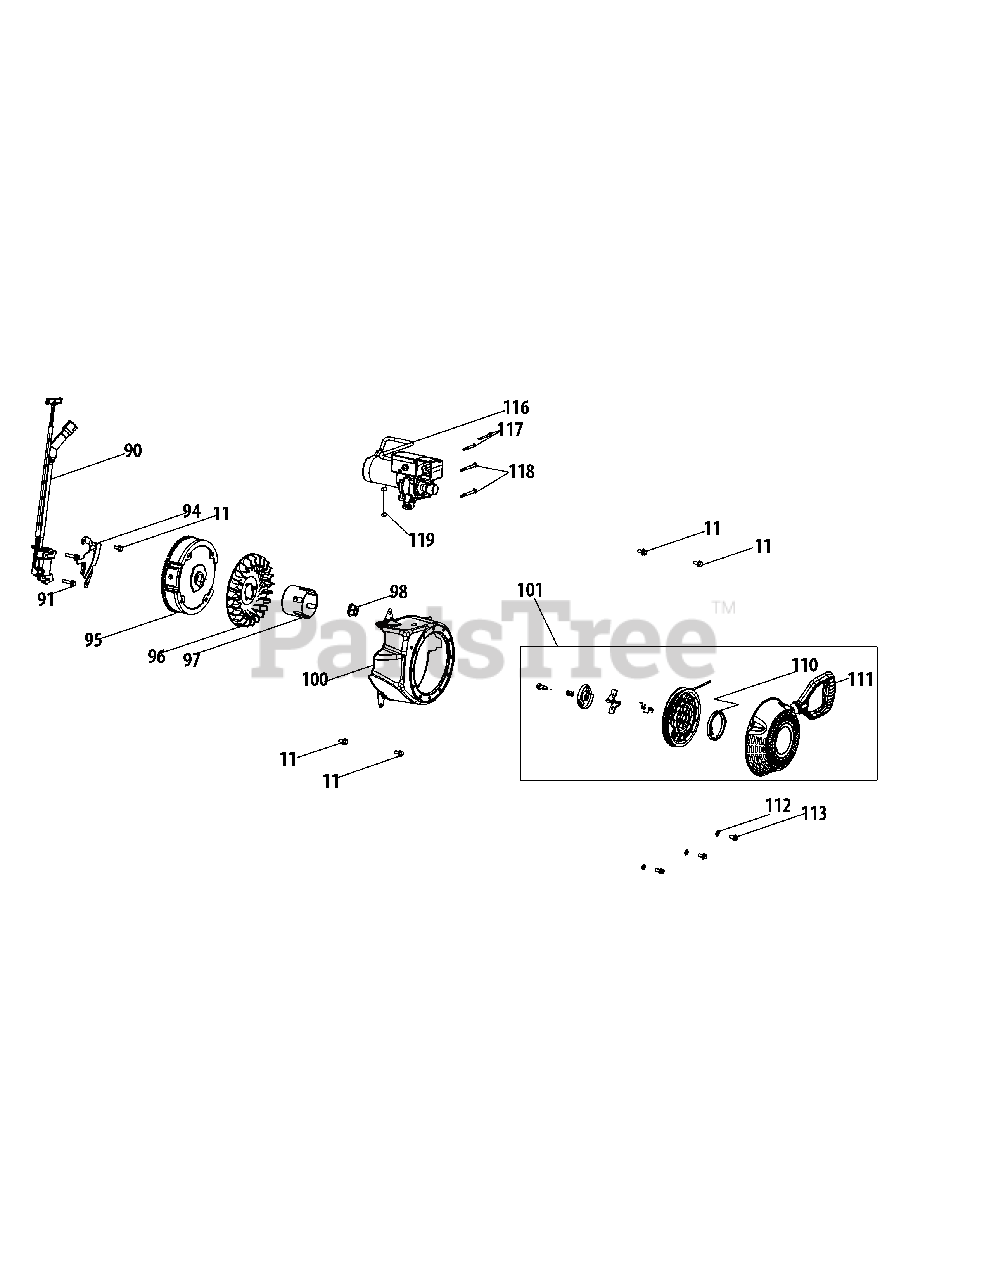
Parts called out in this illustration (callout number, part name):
11	Bolt, M6×12
90	Ignition Module
91	Bolt, M6×25
94	Lower Shield
95	Flywheel
96	Cooling Fan
97	Starter Cup
98	Nut, M14×1.5
100	Blower Housing
101	Recoil Starter
110	Recoil Spring
111	Starter Handle
112	Washer, 6
113	Bolt, M6×10
114	Stop Switch Key
116	Electric Starter
117	Screw, M4×45
118	Bolt, M6×32
119	Pin, 8×8
